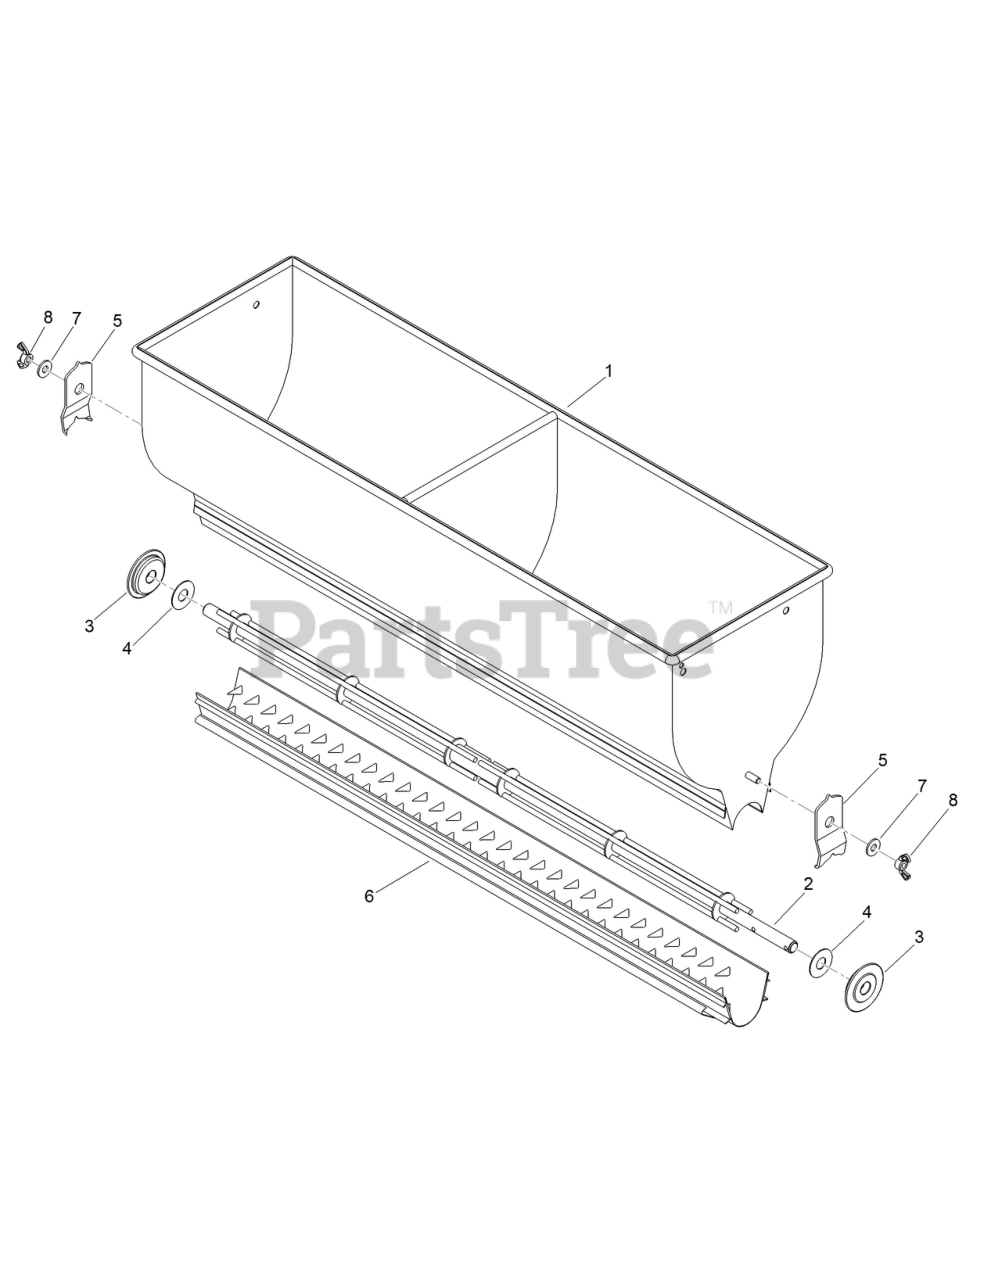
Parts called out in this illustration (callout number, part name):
1	Hopper-36 In. Seeder
2	Rotor-Bar 36 In. Seeder
3	Bearing-End Hopper
5	Retainer-End Bearing
6	SLIDE-METERING GATE
7	WASHER-FLAT
8	WINGNUT-NYLOCK
